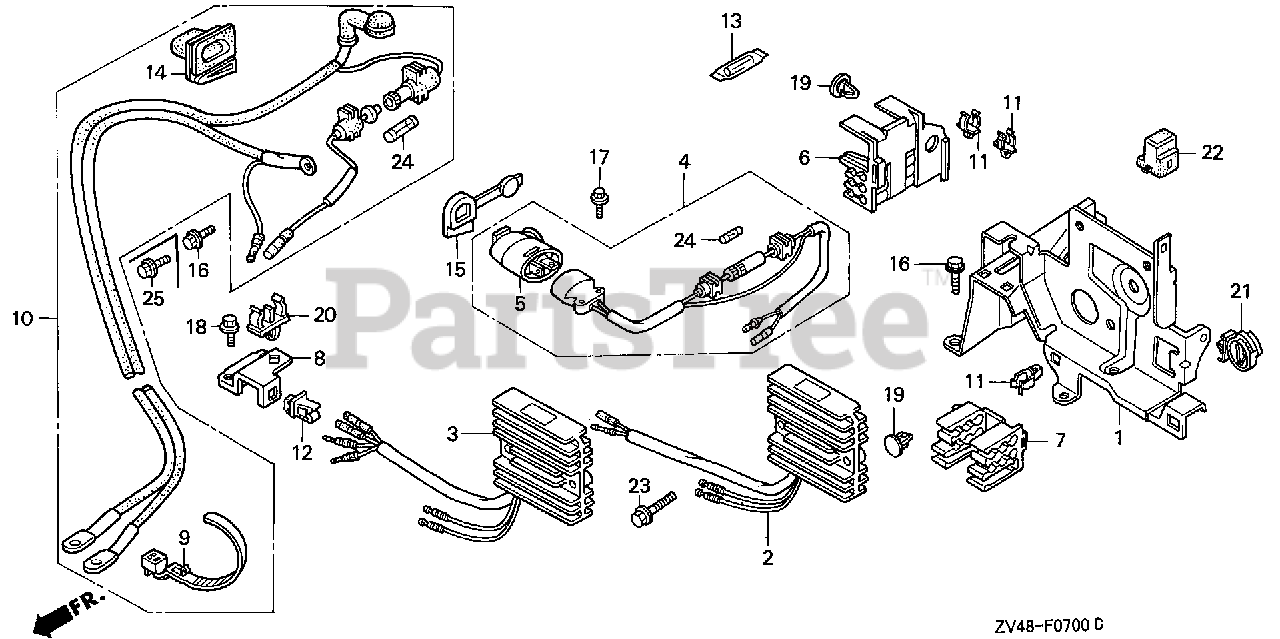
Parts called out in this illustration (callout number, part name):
1	BRACKET, NEUTRAL START CABLE
3	RECTIFIER ASSY., REGULATOR (12A)
6	BRACKET, CONNECTOR (A)
7	BRACKET, CONNECTOR (B)
8	BRACKET, SHIFT CABLE CLIP
9	BAND, WIRE
10	CABLE ASSY., STARTER
11	CLIP, WIRE
12	CLIP B, AIR TEMPERATURE SWITCH WIRE
13	FUSE, SPARE (15A)
14	GROMMET C, OIL CASE
16	BOLT, FLANGE (6X12)
18	BOLT, FLANGE (5X10)
19	CLIP, ANCHOR
20	CLIP, FUEL TUBE
21	CLIP, HARNESS
22	CAP (090 2P)
23	BOLT, FLANGE (6X20)
24	FUSE (15A)
